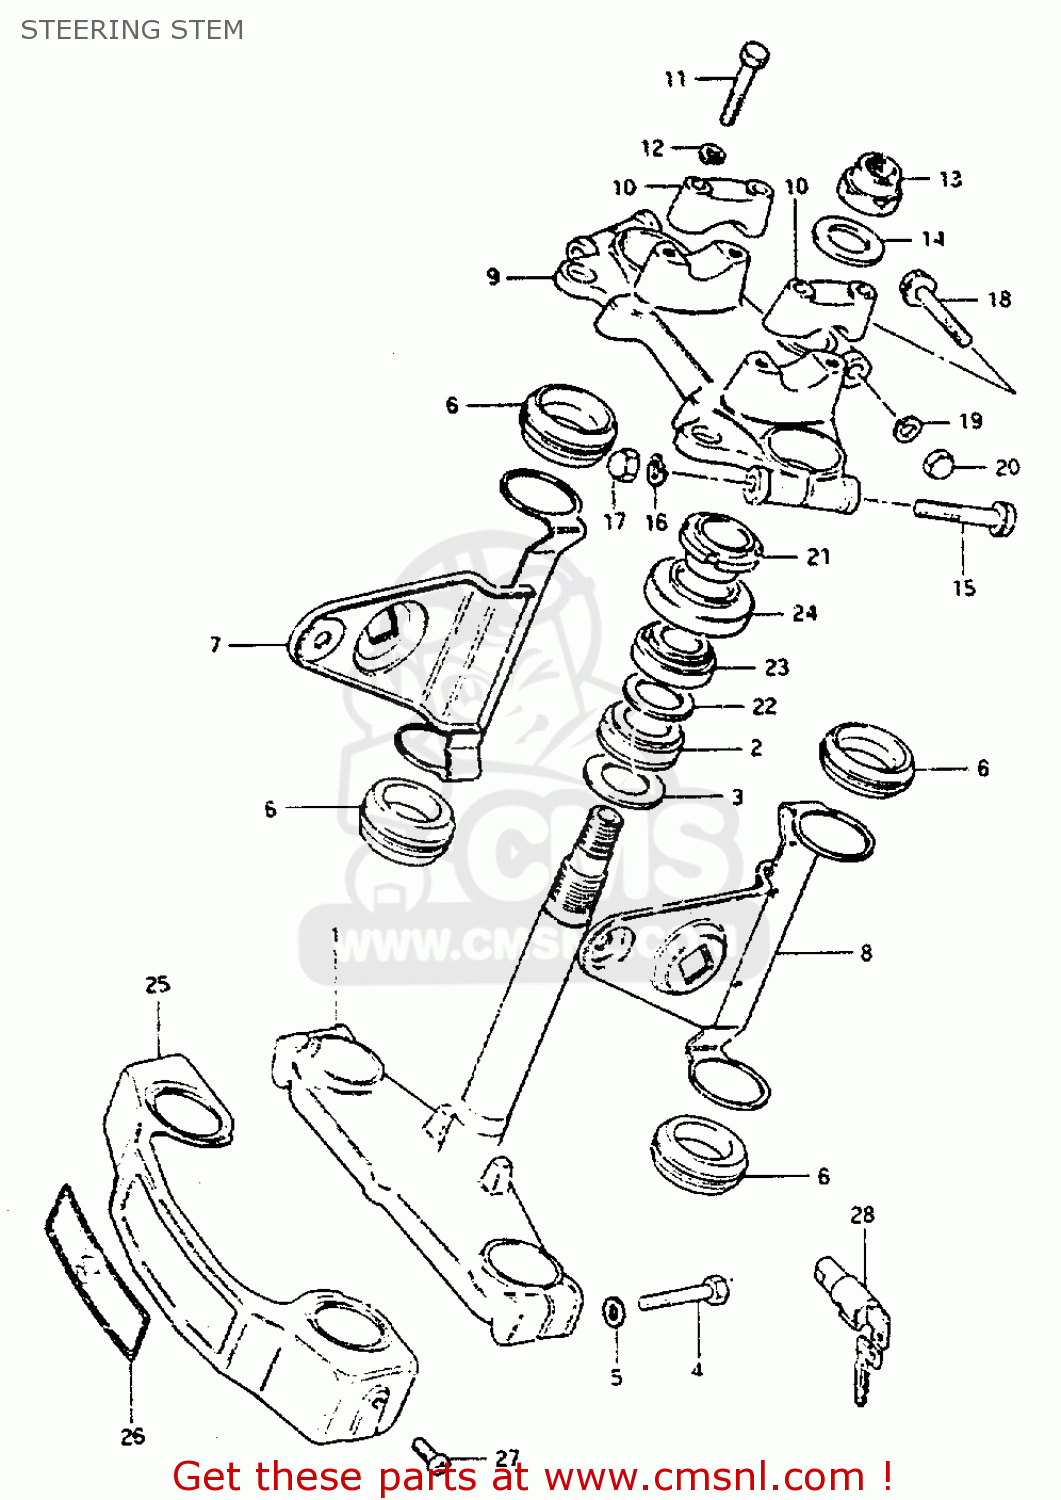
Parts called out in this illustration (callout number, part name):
1	STEM,STEERING
2	BEARING
3	WASHER,THRUST
4	BOLT 8X45
5	WASHER,LOCK,8.
6	CUSHION,HEADLAMP BRACKET
7	BRACKET,HEADLAMP,RIGHT
8	BRACKET,HEADLAMP,LEFT
9	HEAD,STEERING STEM
10	HOLDER,HANDLE UPR
11	BOLT
12	LOCK WASHER
13	NUT,FR FORK UPR BRACKET
14	WASHER
15	BOLT 10X55
16	LOCK WASHER
17	NUT
18	BOLT
19	LOCK WASHER
20	NUT
21	NUT,STEERING STEM
22	WASHER(18.5X24X1)
23	TAPER,ROLLER BEARING
24	DUST SEAL,STEERING,UPPER
25	COVER,FRONT FORK
26	EMBLEM,FR FORK COVER
27	SCREW 5X6
